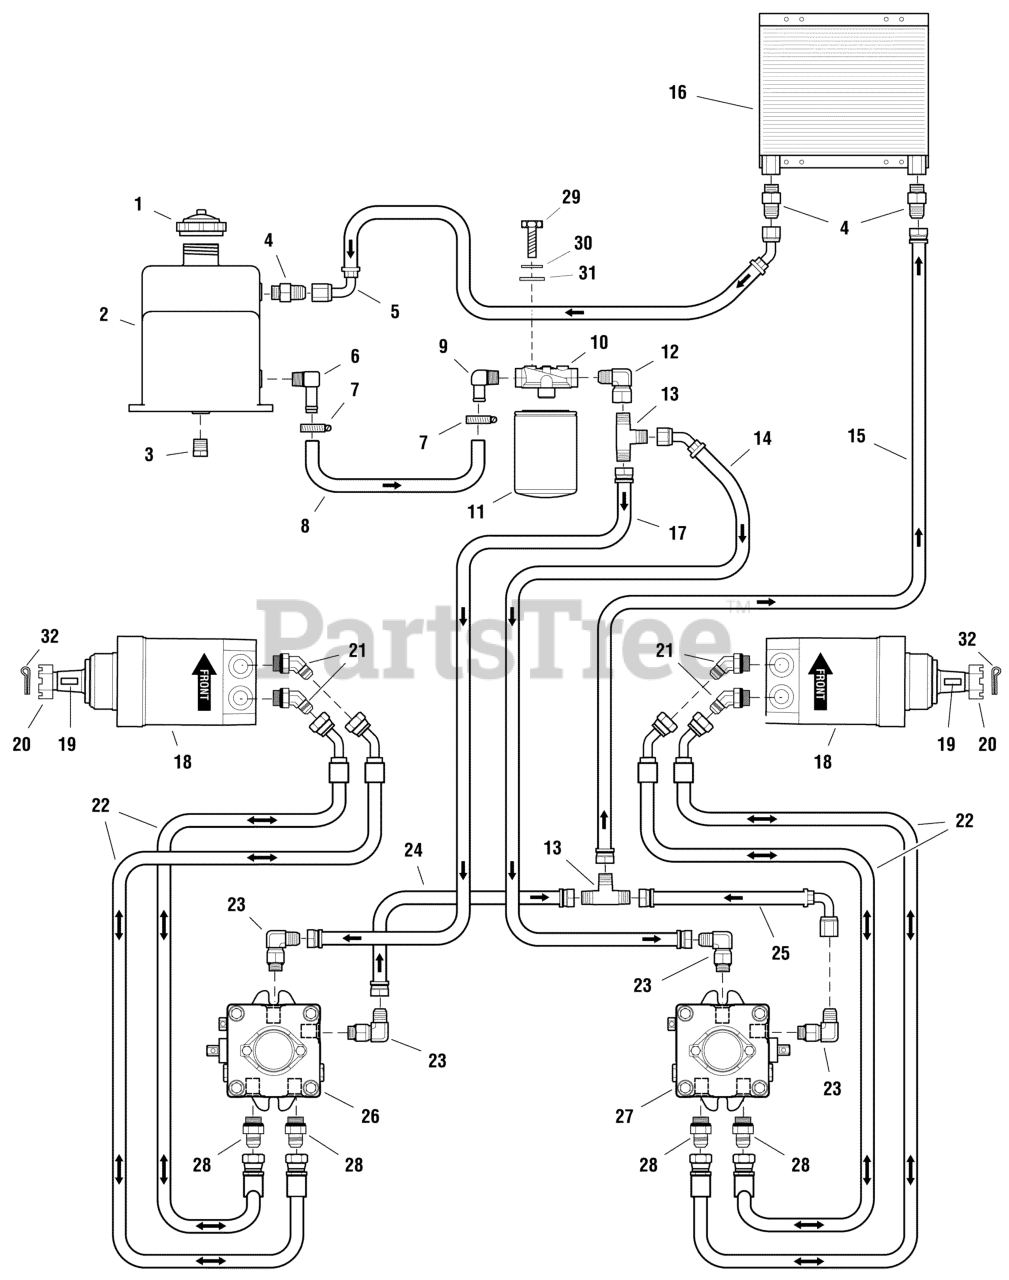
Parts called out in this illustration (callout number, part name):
1	CAP, 2-1/2" VENTED
2	HYDRAULIC OIL RESERVOIR
3	PLUG, 1/2" NPT, SQUARE HEAD
4	FITTING, #8 JIC - 1/2" NPT, STRAIGHT
5	HOSE ASSEMBLY, 48"
6	FITTING, 1/2NPT-5/8" HOSE, 90D
7	CLAMP, #10 HOSE, STAINLESS
8	HOSE, 5/8 PUSH-LOCK, 13.00"
9	FITTING, 1/2NPT-5/8" HOSE, 90D
10	FILTER HEAD
11	FILTER, HYDRAULIC, SERVICE PART (PKG)
12	FITTING, #8 JIC F - 1/2" NPT, 90 DEG.
13	FITTING, TEE, JIC #8
14	HOSE ASSEMBLY, 28"
15	HOSE ASSEMBLY, 49"
16	OIL COOLER 1.5" X 8.5"" X 11
17	HOSE ASSEMBLY, 42"
18	WHEEL MOTOR, TF0405UB080AADD MB 25 SERIES
19	KEY
20	NUT, CASTLE, 1-20
21	FITTING, #8 JIC - #10 O-RING, 45 DEG.
22	HOSE ASSEMBLY, (29)
23	FITTING, #8 JIC - #8 O-RING, 90 DEG.
24	HOSE ASSEMBLY, 14"
25	HOSE ASSEMBLY, 7"
26	HYDRAULIC PUMP - LH
27	HYDRAULIC PUMP - RH
28	ADAPTER, HYD.
29	BOLT, 1/4-20 X 3/4" GD5 YZ
30	WASHER, 1/4 LOCK
31	WASHER, 1/4 SAE
32	PIN, COTTER, 1/8" X 2"
